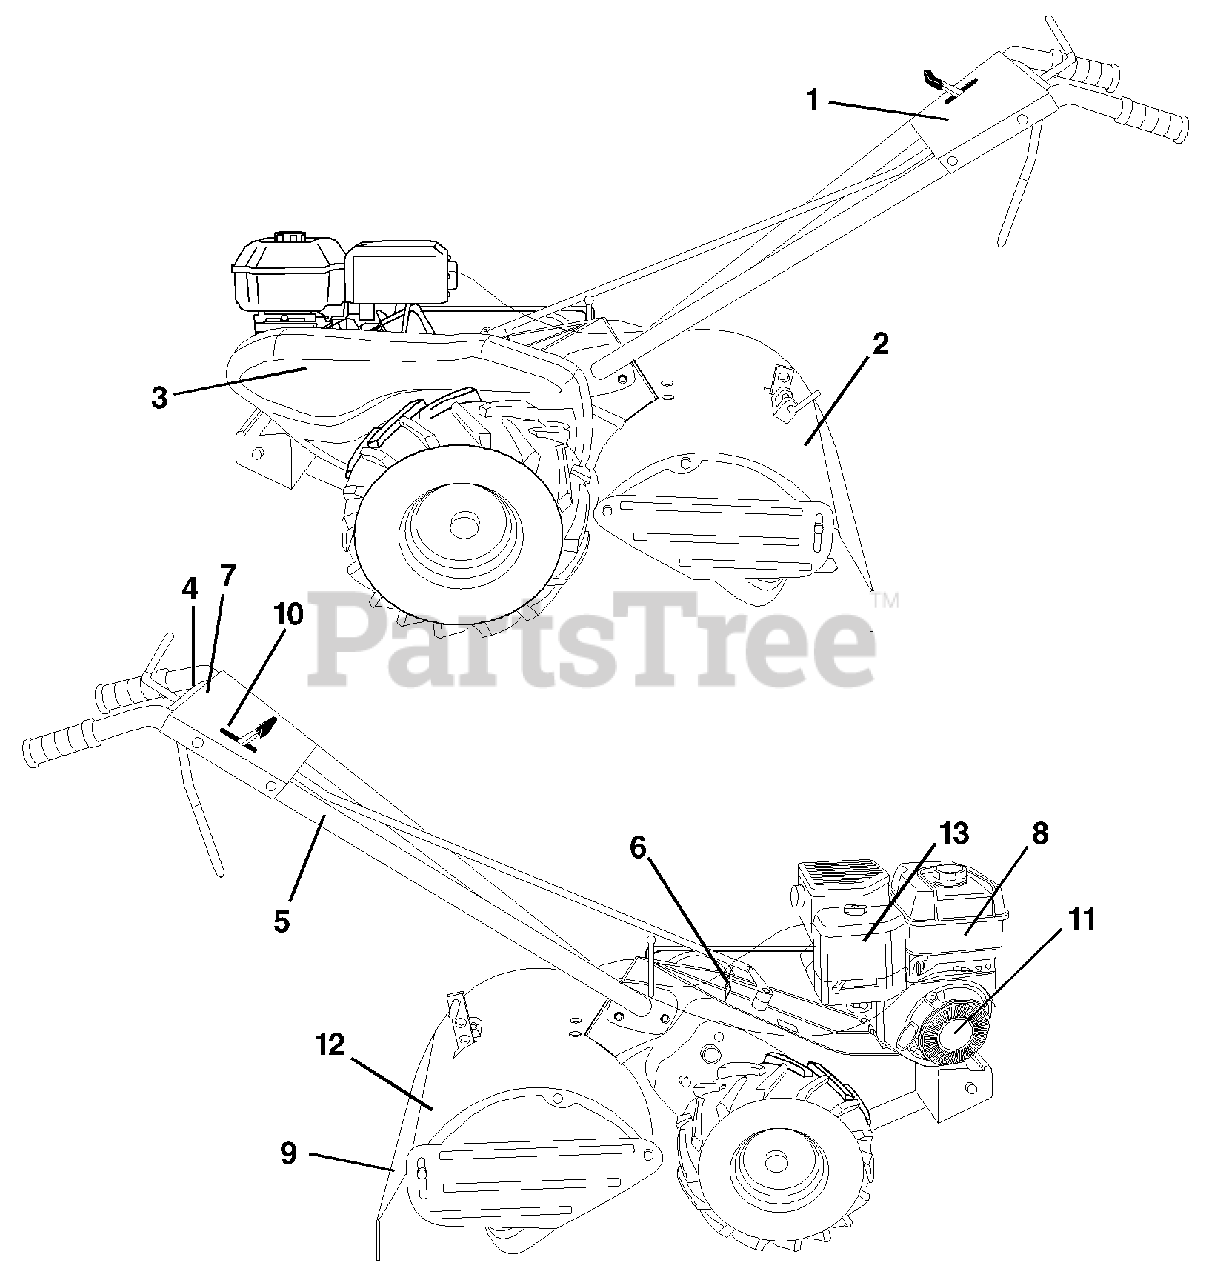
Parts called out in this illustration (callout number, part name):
1	Decal, Logo
2	Decal, Logo
3	Decal, Logo
4	Decal, Instruction, Tilling
5	Decal, Hand Placement
6	Decal, Shift Indicator
7	Decal, Pnl Cntrl Reverse
8	Decal, OHV.N-I/C
9	Decal, Warning, Rotating Tines
10	Decal, Throttle
11	Decal, Rewind Intek
12	Decal, Warning Till
13	Decal, B&S Tiller
